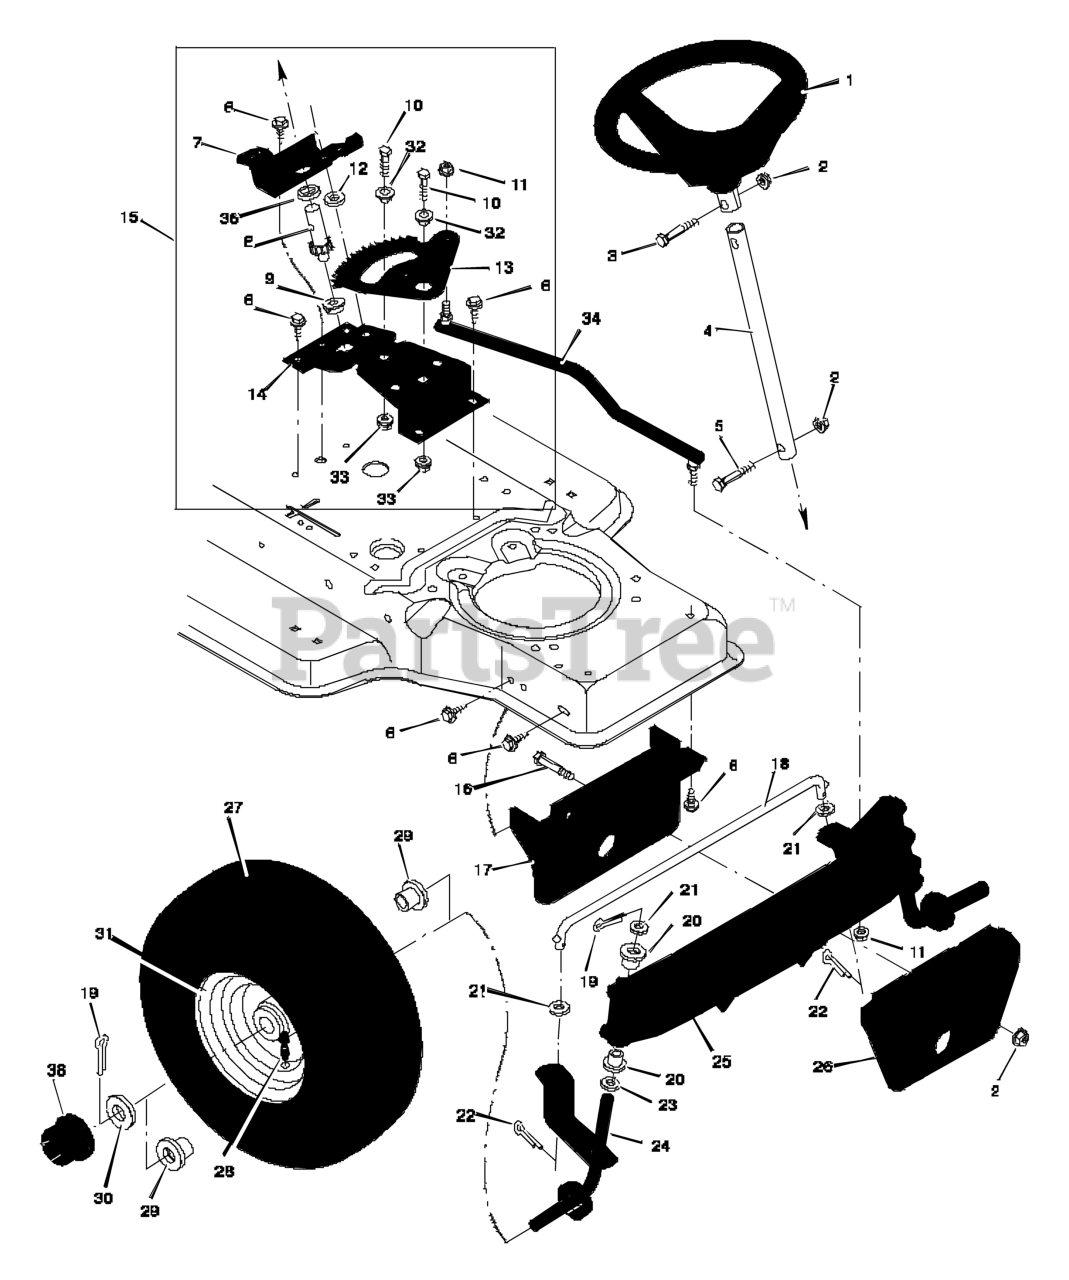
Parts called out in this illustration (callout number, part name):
1	Wheel, Steering
2	Nut, Hex
3	Bolt, Hex
4	Post, Steering
5	Bolt, Hex
7	Bracket, Sector
8	Gear, Pinion
9	Bearing
10	CAPSCREW, Hex Head, 5/16-18 x 1
11	Locknut, Flange
13	Gear, Sector
14	Bracket, Sector
15	Kit, Steering Gear
16	Bolt, Hex
17	Support, Rear Axle
18	Rod, Tie
19	Pin, Cotter
20	Bearing
22	Pin, Cotter
24	Spindle Assembly, Right
25	Spindle Assembly, Axle & Left
26	Support, Front Axle
28	Stem, Valve
29	Bearing, Wheel
31	Wheel & Tire Assembly
32	Bearing
33	Locknut, Flange
34	Link, Drag
36	Spacer, Pinion Gear
38	Hub Cap
